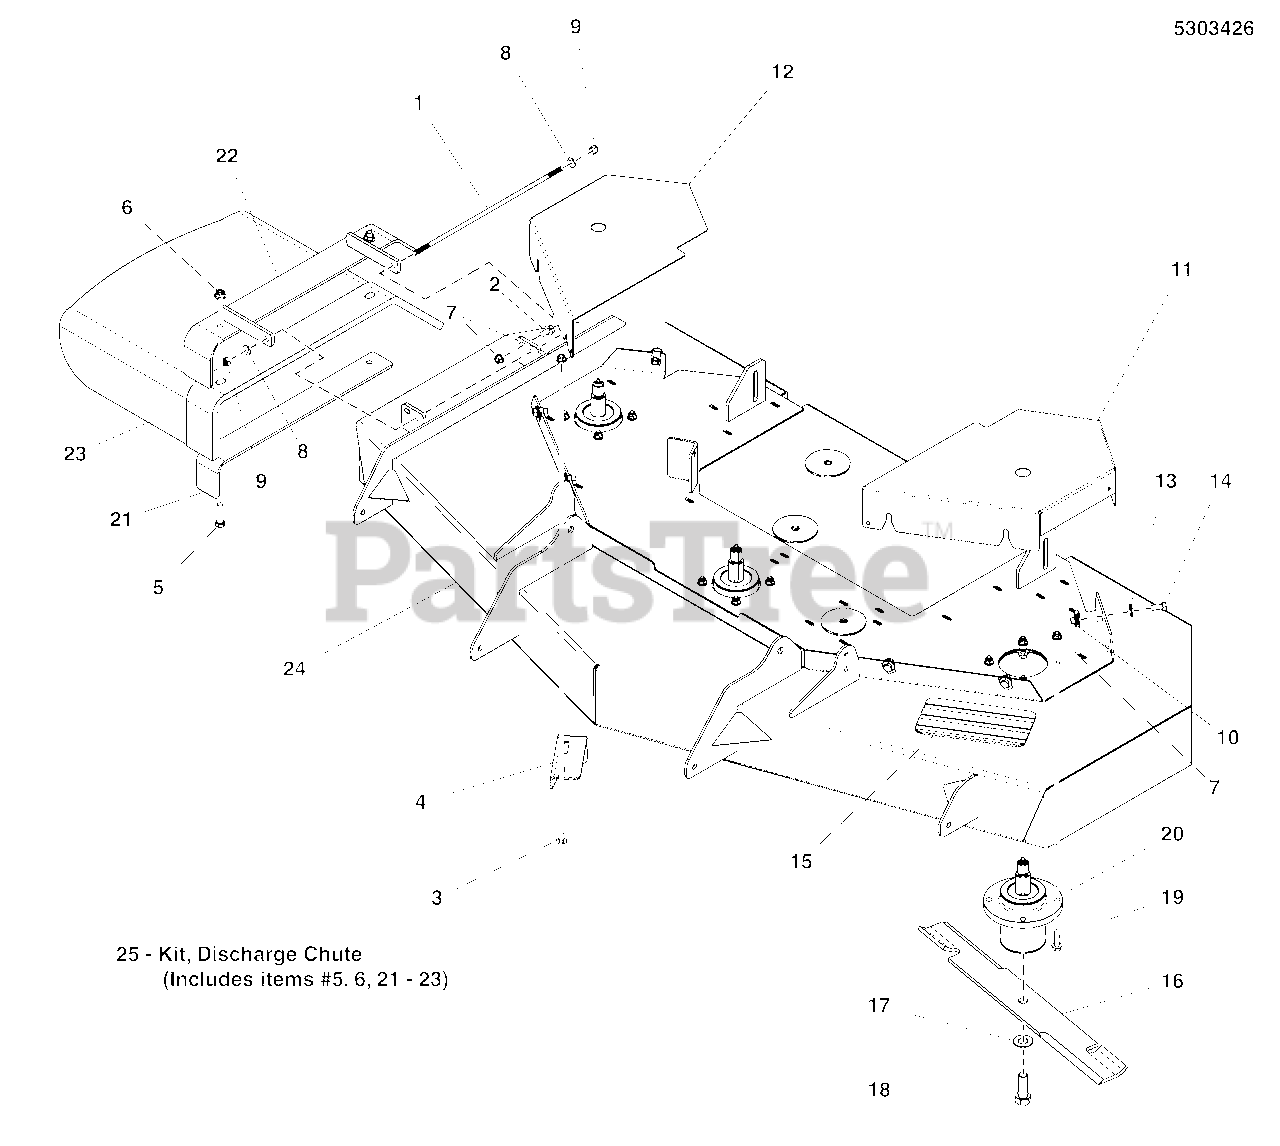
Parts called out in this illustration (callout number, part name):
1	ROD, 5/16 X 13.75, TBE, CZ
2	SCREW, 5/16-18
3	BOLT, 5/16-18 X 3/4, CARRIAGE
4	PLATE, DEFLECTOR - BLK
5	BOLT, 3/8-16 X 1-1/2 GD5 YZ
6	NUT, 3/8-16 HEX NYLOCK FLANGE
7	NUT, 5/16-18 HEX NYLOCK FLANGE
8	WASHER, 5/16 SAE
9	NUT, 5/16-24 HEX NYLON LOCK
10	BODY CLIP, 5/16-18-7GA MATERIAL
11	GUARD 61" - LH - RED
12	GUARD 61" - RH - RED
13	WASHER, 5/16 F436 FLAT
14	BOLT, 5/16-18 X 3/4 GD5
15	SAFETY WALK, 4.00 X 7.50
16	BLADE SET, .187 X 2.50 X 21.00 (3) (SV)
16	BLADE, .187 X 2.50 X 21.00
17	WASHER, 5/8 GRADE 8, YZ
18	BOLT, 5/8-11 X 1-3/4 GD8
19	BOLT, 5/16-18 X 1 1/4 FLANGE
20	ASSM, SPINDLE, LOW PROFILE
21	SUPPORT, DISCHARGE CHUTE, 48/52
22	WELD, FRAME CHUTE, 44/48/52 - BLK
23	CHUTE, DISCHARGE, BEND RUBBER, 44/48/52
24	DECK SHELL W/DECALS, 61, 550Z/2950 (SV)
